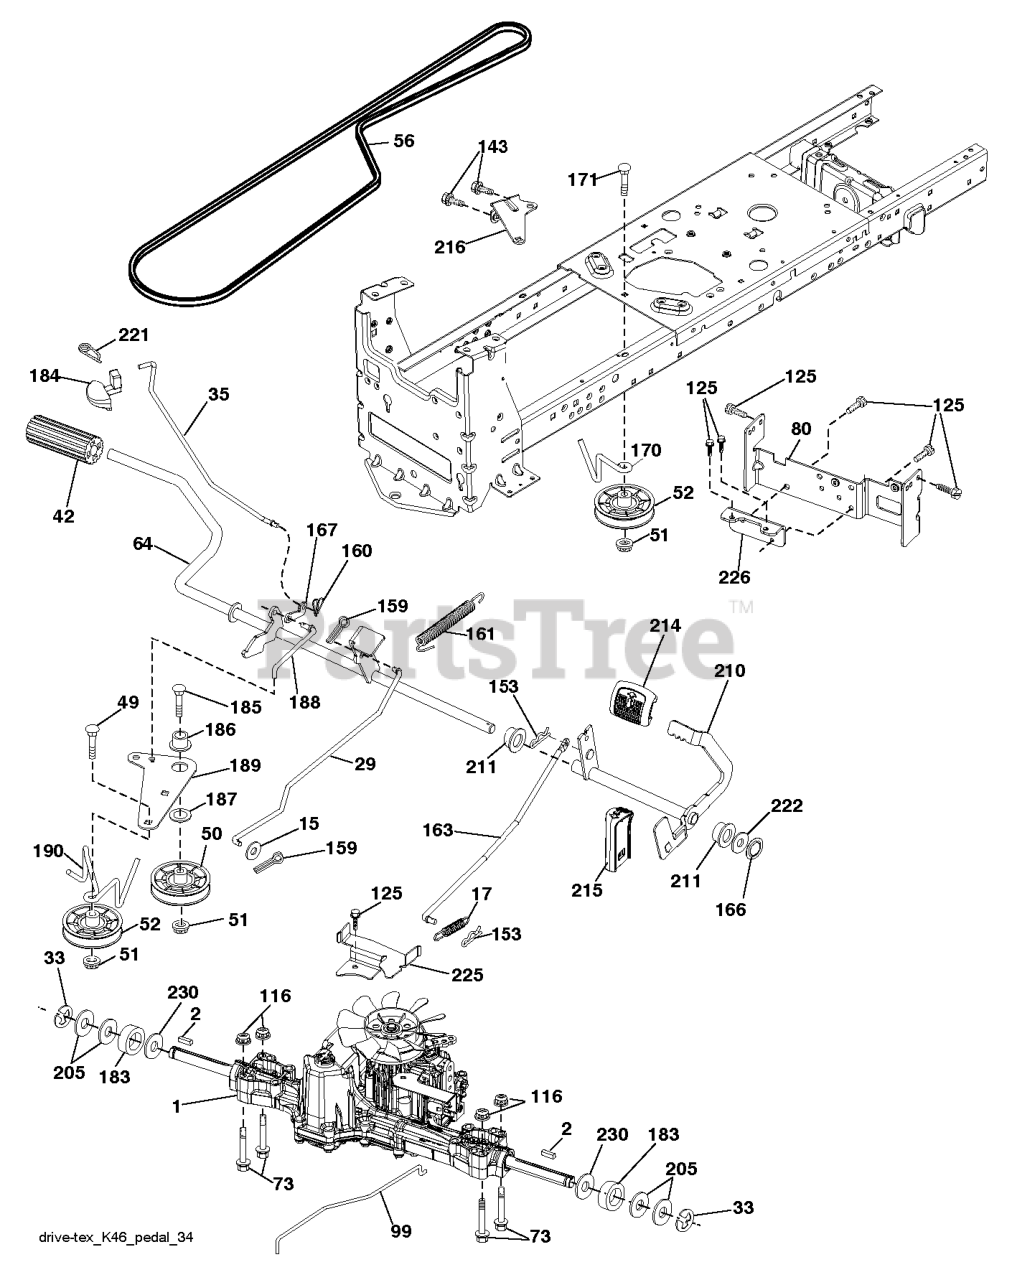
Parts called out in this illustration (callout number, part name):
2	SQUARE KEY
15	WASHER
17	SPRING.BRAKE.K46.GREEN
29	ROD.BRAKE.K46
35	ROD.CNTRL.PARK.PREDATOR.LT.TEX
42	PEDAL COVER T
50	IDLER.FLAT.910.OFFSET
51	NUT LOCK FLG 3/8-16 UNC
52	IDLER.V-GROOVE.910.OFFSET
56	V-BELT.MOWER.92.40.42/K46
64	SHAFT.ASM.PEDAL.BRK.CNTR
73	BOLT HEX 5/16-18 GR 5
80	STRAP TORQUE
99	ROD.SPRING.BYPASS.K46.LT.Z
116	NUT LOCK HEX FLANGE 5/16-18
125	SCREW
143	Screw 5/16-18 x 1/2 Hex, Self Tapping 5/16-18 x 1/2
153	RETAINER M
159	COTTER PIN
160	RETAINER CLIP
161	SPRING, RETURN LT
163	ROD.CONTROL.PEDAL.K46
166	NUT.PUSH.625
167	LATCH.BRAKE.SPRING
170	KEEPER.V-IDLER.CENTER.
171	BOLT
183	SPACER AXLE
184	HANDLE PARKING BRAKE
186	SPACER.RETAINER
187	WASHER 12/32X2X10GA
188	RP.LINK.CLUTCH.GROUND.DRIVE
189	BELLCRANK.GROUND.DRIVE.TEX.
190	KEEPER.BELLCRANK.DRIVE
210	ROCKER.ASM.PEDAL.CONTR
211	BEARING.NYLON
214	PEDAL.FORWARD.PAD.TEX
215	PEDAL.REVERSE.TEX.GT.4
216	BRACKET.PULLEY.IDLER.W/TEX
221	RETAINER.SPRING.CLIP.H
222	WASHER 21/32 X 1-1/4 X 10 GA.
225	KEEPER.BELT.TRANSAXLE.K46
226	BRACKET.MOUNT.TORQUE.K46.TLT
230	WASHER.HARDENED
